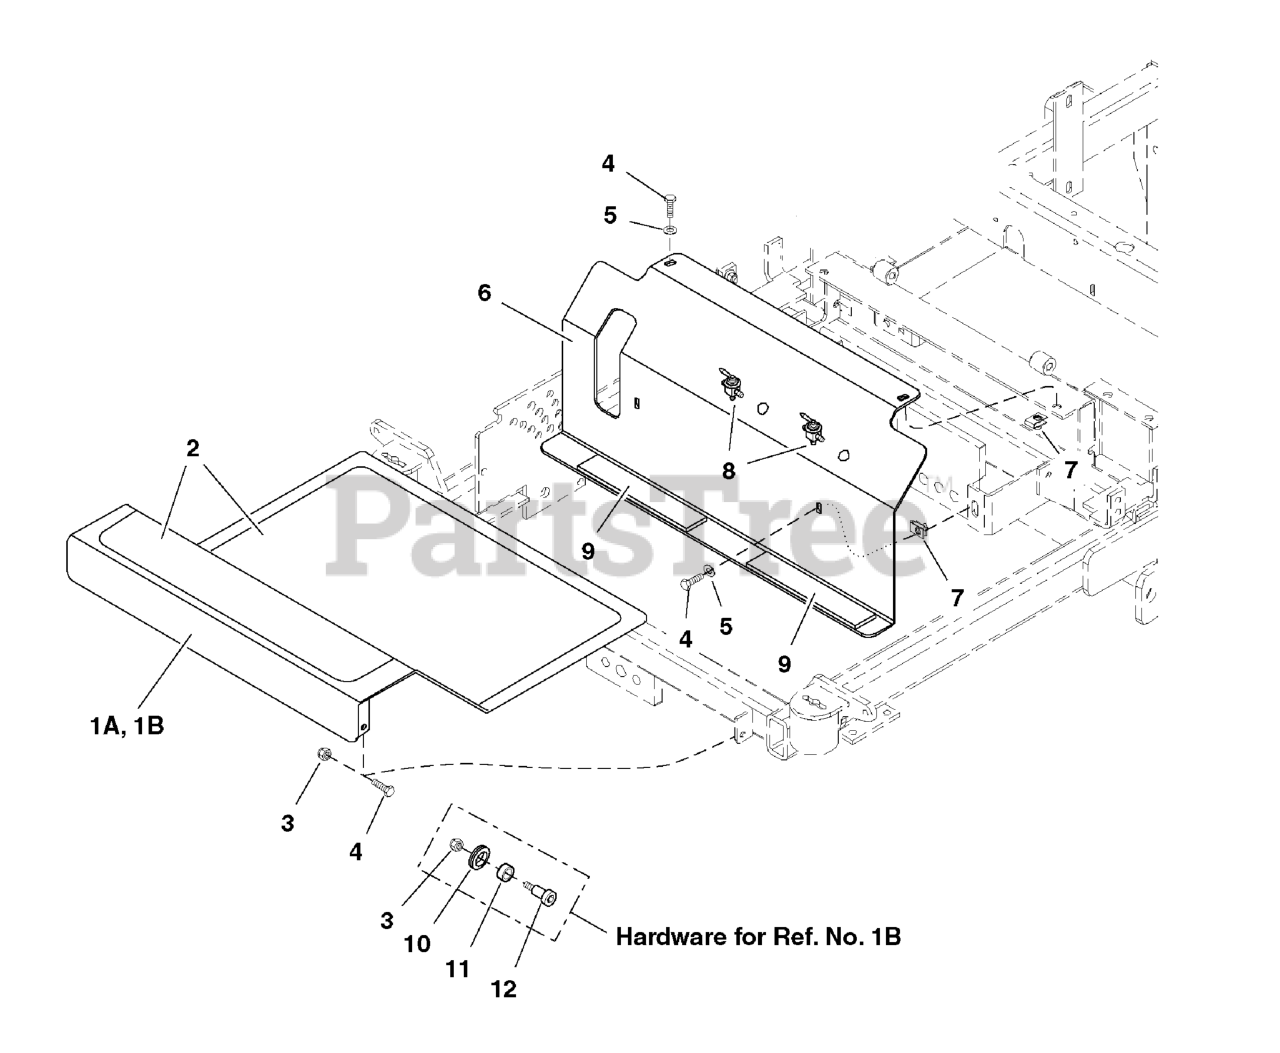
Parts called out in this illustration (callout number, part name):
1A	FLOOR PAN
1B	FLOOR PAN
2	SAFETY WALK, 11.50 X 19.00
3	NUT, 5/16-18 Hex Nylon Lock
4	BOLT, 5/16-18 X 1 GD5 YZ
5	WASHER, 5/16" SAE
6	BRAKE COVER PANEL
7	BODY CLIP, 5/16-18-7GA MATERIAL
8	VALVE, Fuel Shut Off
9	RUBBER PAD
10	GROMMET
11	SLEEVE
12	SHOULDER BOLT, 3/8 x 5/8
